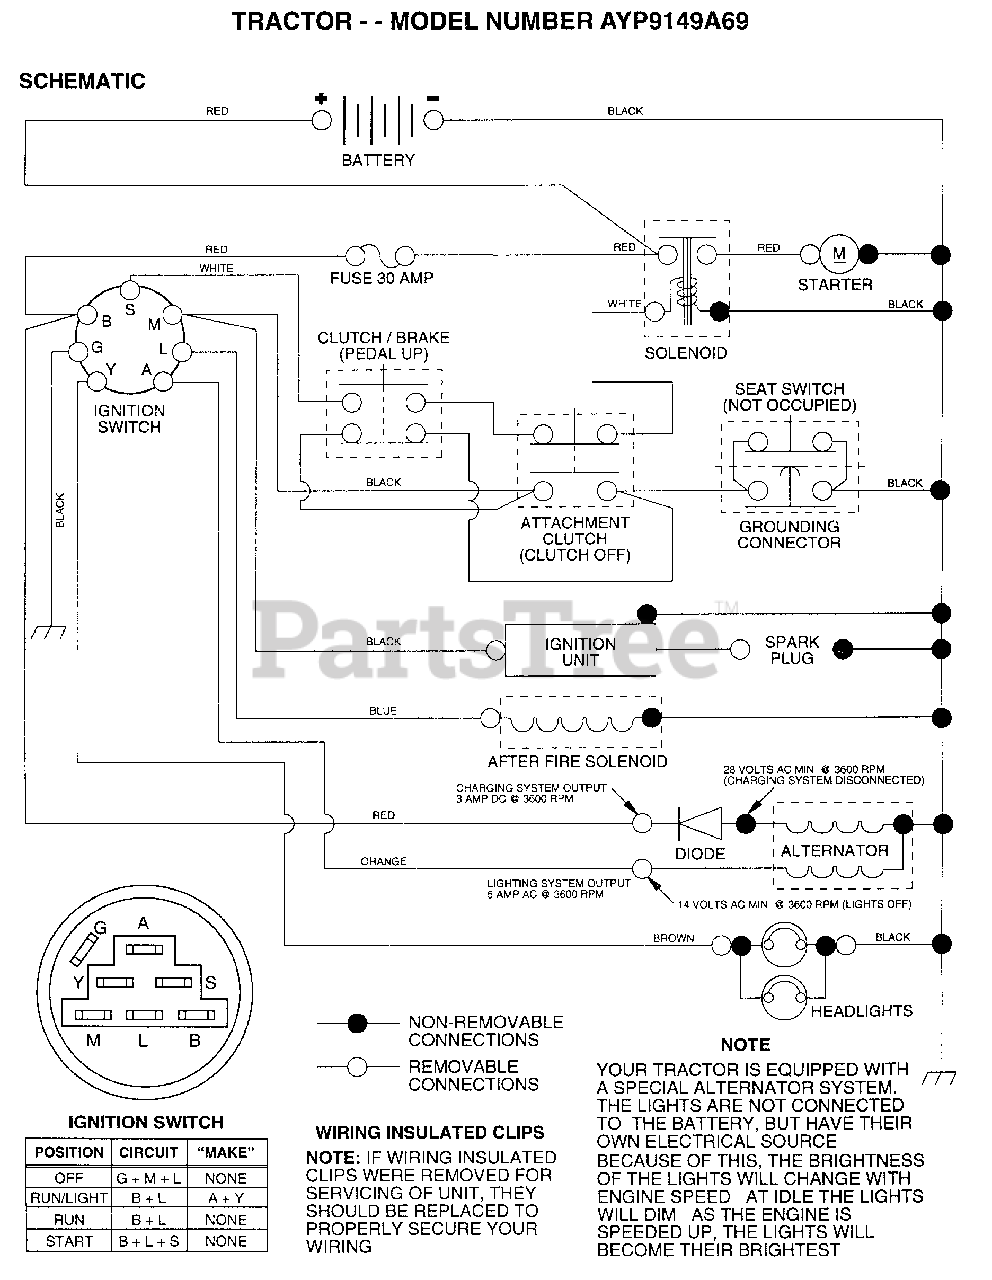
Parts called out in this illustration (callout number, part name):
2	BOLT LT
3	WASHER
4	LOCKWASHER
7	TUBE T
9	HOSE CLAMP T
15	FASTNER.SNAP-IN
20	NUT
21	"HARNESS,LIGHT SOC"
22	HEADLAMP BULB
24	"CABLE T, BATTERY"
25	CABLE.BTRY.6GA.RD
26	FUSE HYT
28	CABLE T
29	SWITCH SEAT
30	SWITCH IGN 4POS
31	NUT IGNITION
32	COVER KEY SWITCH
33	KEY
35	BRACKET LT
36	SCREW
38	BRACKET SWITCH IN
39	SWITCH INTERLOCKT
41	BOLT HXHD FIN
44	NUT HXKEP 1/4X20
48	ADAPTER AMMETER
52	PROTECTION LOOP
70	HARNESS ENGINE
